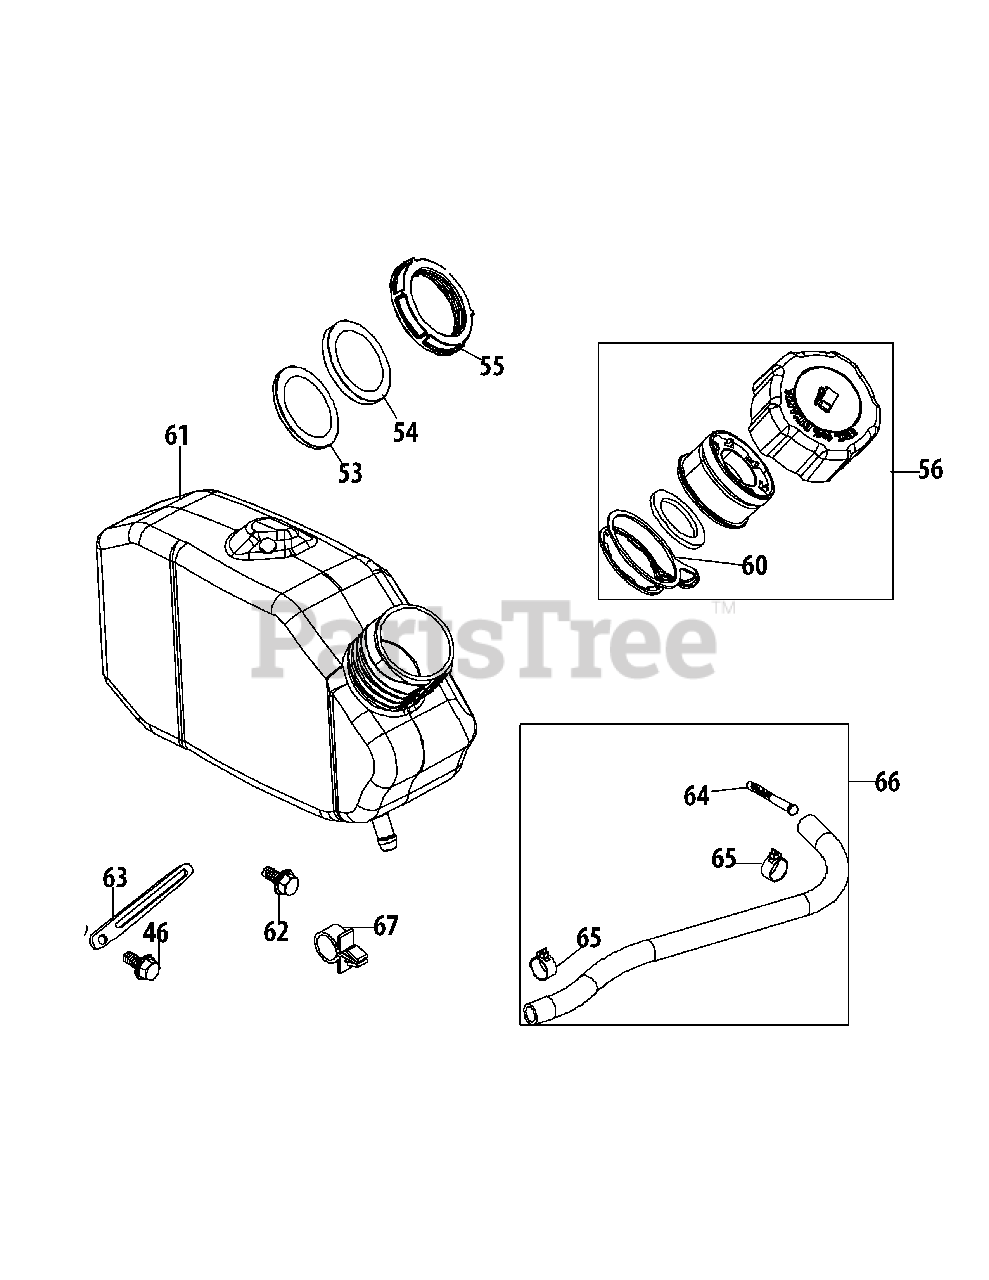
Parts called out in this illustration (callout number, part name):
46	Bolt M6X14 Multi-Purpose
53	Fuel Tank Lower Grommet
54	Fuel Tank Upper Grommet
55	Fuel Tank Nut
56	Fuel Cap Assembly
60	Fuel Cap Tether
61	Fuel Tank
62	Bolt M6X12 Multi-Purpose
63	Flexible Clamp, Vent Hose
64	Fuel Filter
65	Fuel Hose Clamp
66	Fuel Hose
67	Plastic Support Clamp
